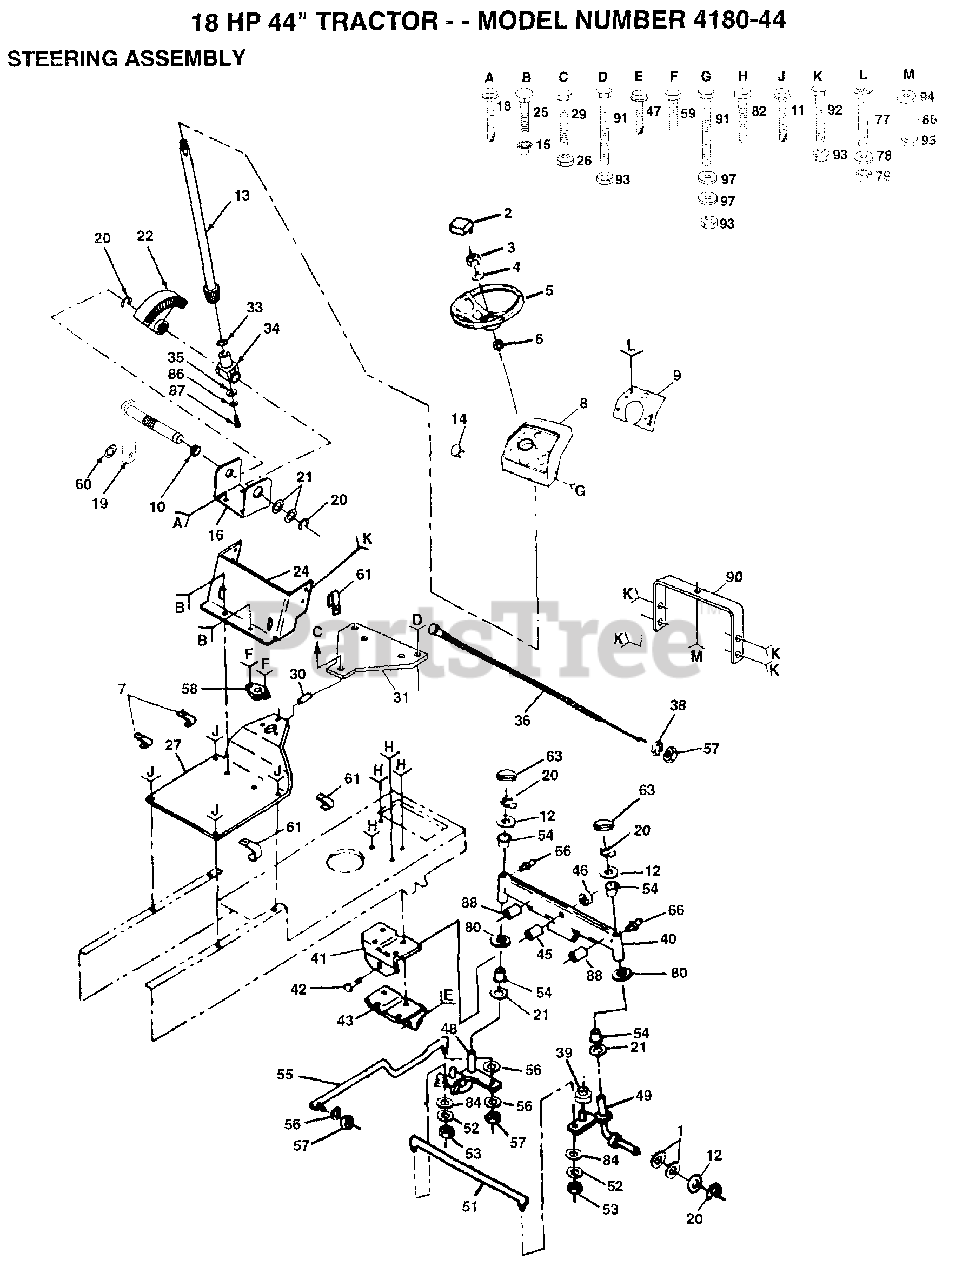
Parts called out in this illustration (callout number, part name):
1	WASHER
2	"INSERT,STR WHEEL"
4	WASHER
6	ADAPTER LT
7	"CLIP,INSULATOR"
8	DASHBOARD BLACK
9	PLATE SLKSCR YP
10	NYLINER T
11	SCREW
12	WASHER
13	STEERING SHAFT
14	PLUG-DASH T
16	"BRKT,STEERING"
18	SCREW
20	RING
21	WASHER .T
22	GEAR SECTOR
24	LOWER DASH
25	SCREW
26	NUT
29	BOLT
30	SPACER
31	PLATE.SUPT.BATTER
33	THRUST WASHER
34	SUPPORT.SHAFT
36	CHOKE CONTROL
38	LOCKWASHER
39	BUSHING SPIN STOP
40	AXLE ASM FRONT
41	SUPPORT-SADDL T
42	BOLT LT
43	SUPPORT.SADDLE.FT
45	BEARING
46	"NUT-LOC,FLANGE LT"
47	SCREW LT
51	TIE ROD
52	LOCKWASHER
53	NUT.LOCK.5/16-24
54	COL. SRTG. BEAR.
56	LOCKWASHER
60	WASHER
61	CLIP T
63	CAP
66	ZERK M
77	SCREW
78	WASHER
80	WASHER
82	SCREW
84	WASHER M
86	LOCKWASHER
87	"SCREW,SPECIAL"
88	AXLE PIN
90	SUPPORT ASS'Y
91	BOLT
92	BOLT
93	NUT
94	WASHER PM
97	WASHER
